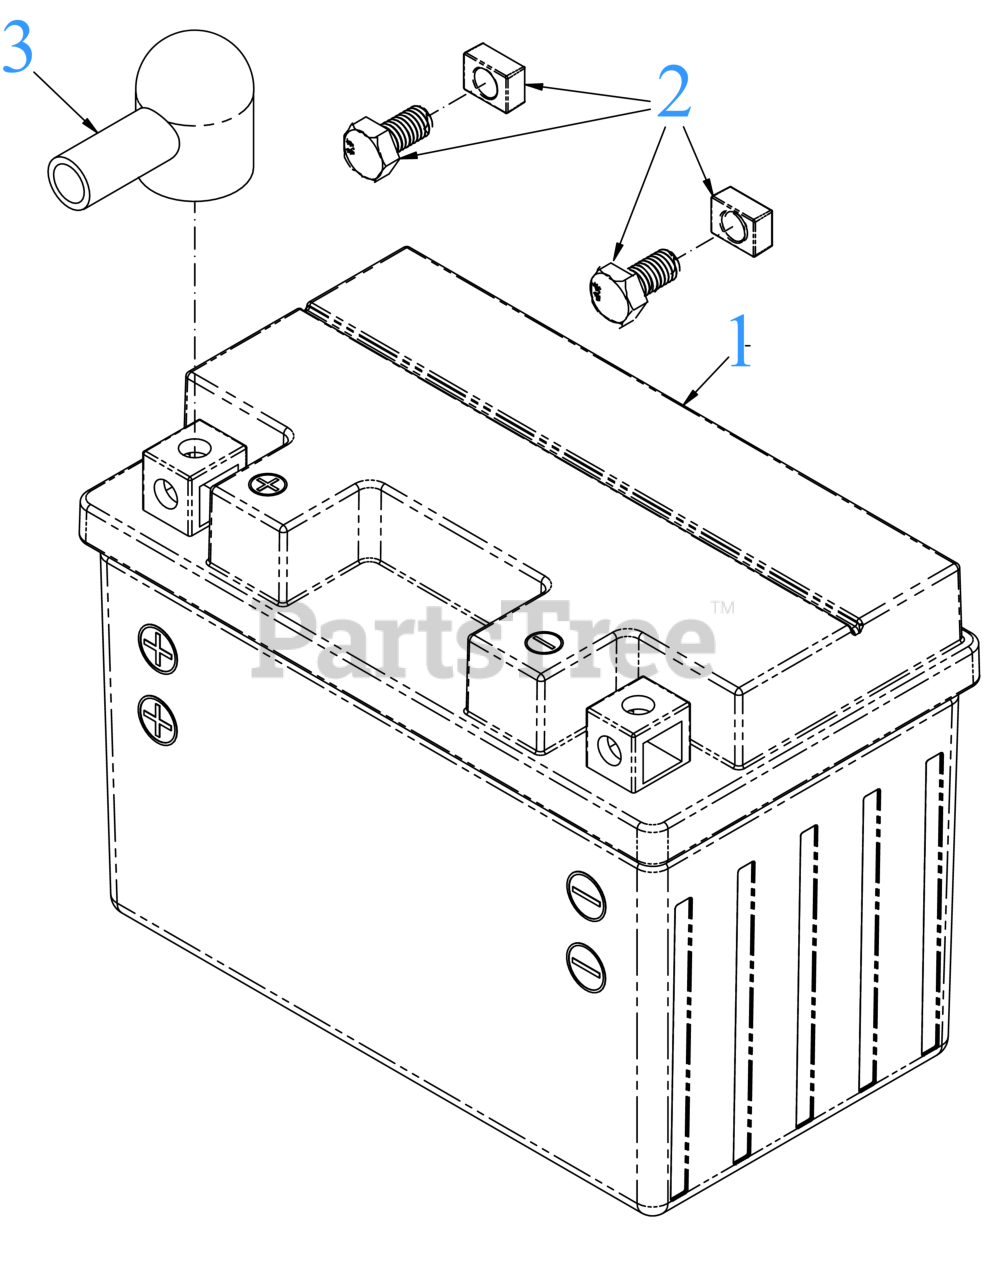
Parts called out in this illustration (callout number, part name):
1	BATTERY (11AHR AGM 210CCA)
2	BATTERY HARDWARE KIT
3	TERMINAL COVER RED
